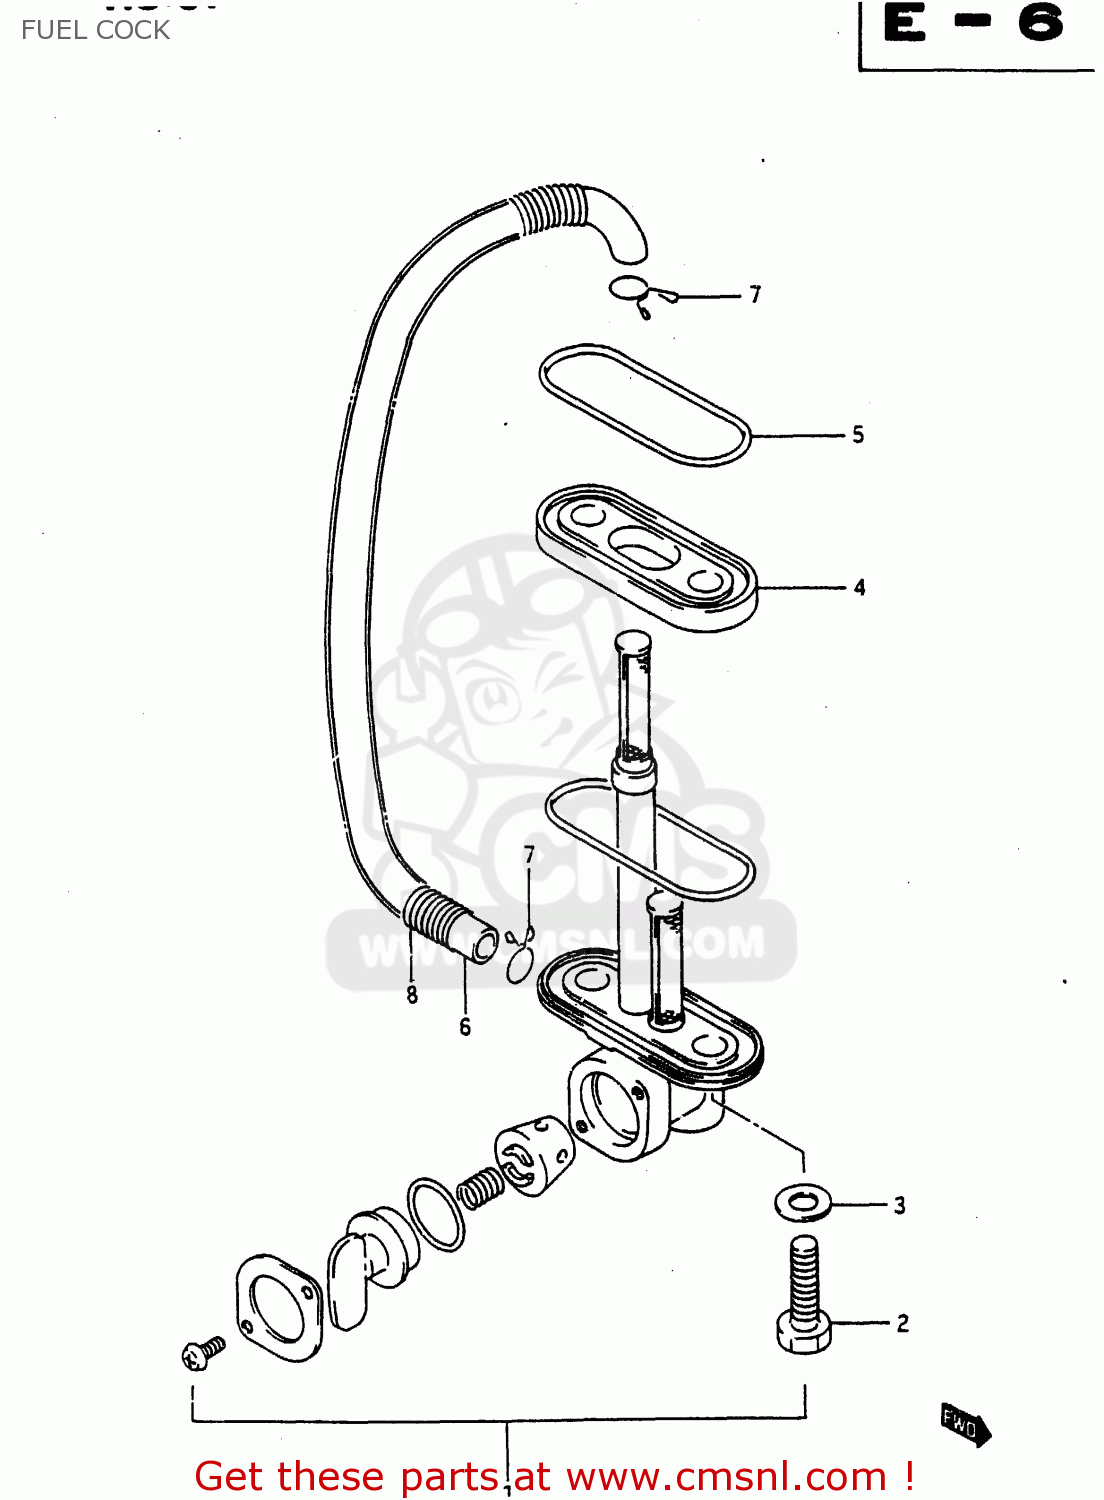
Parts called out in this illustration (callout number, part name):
1	COCK ASSY,FUEL
2	BOLT(6X20)
3	GASKET(6.4X11.5X0.8) (NAS)
4	SPACER,FUEL COCK
5	GASKET,FUEL COCK (NAS)
6	HOSE
7	CLIP
8	SPRING
